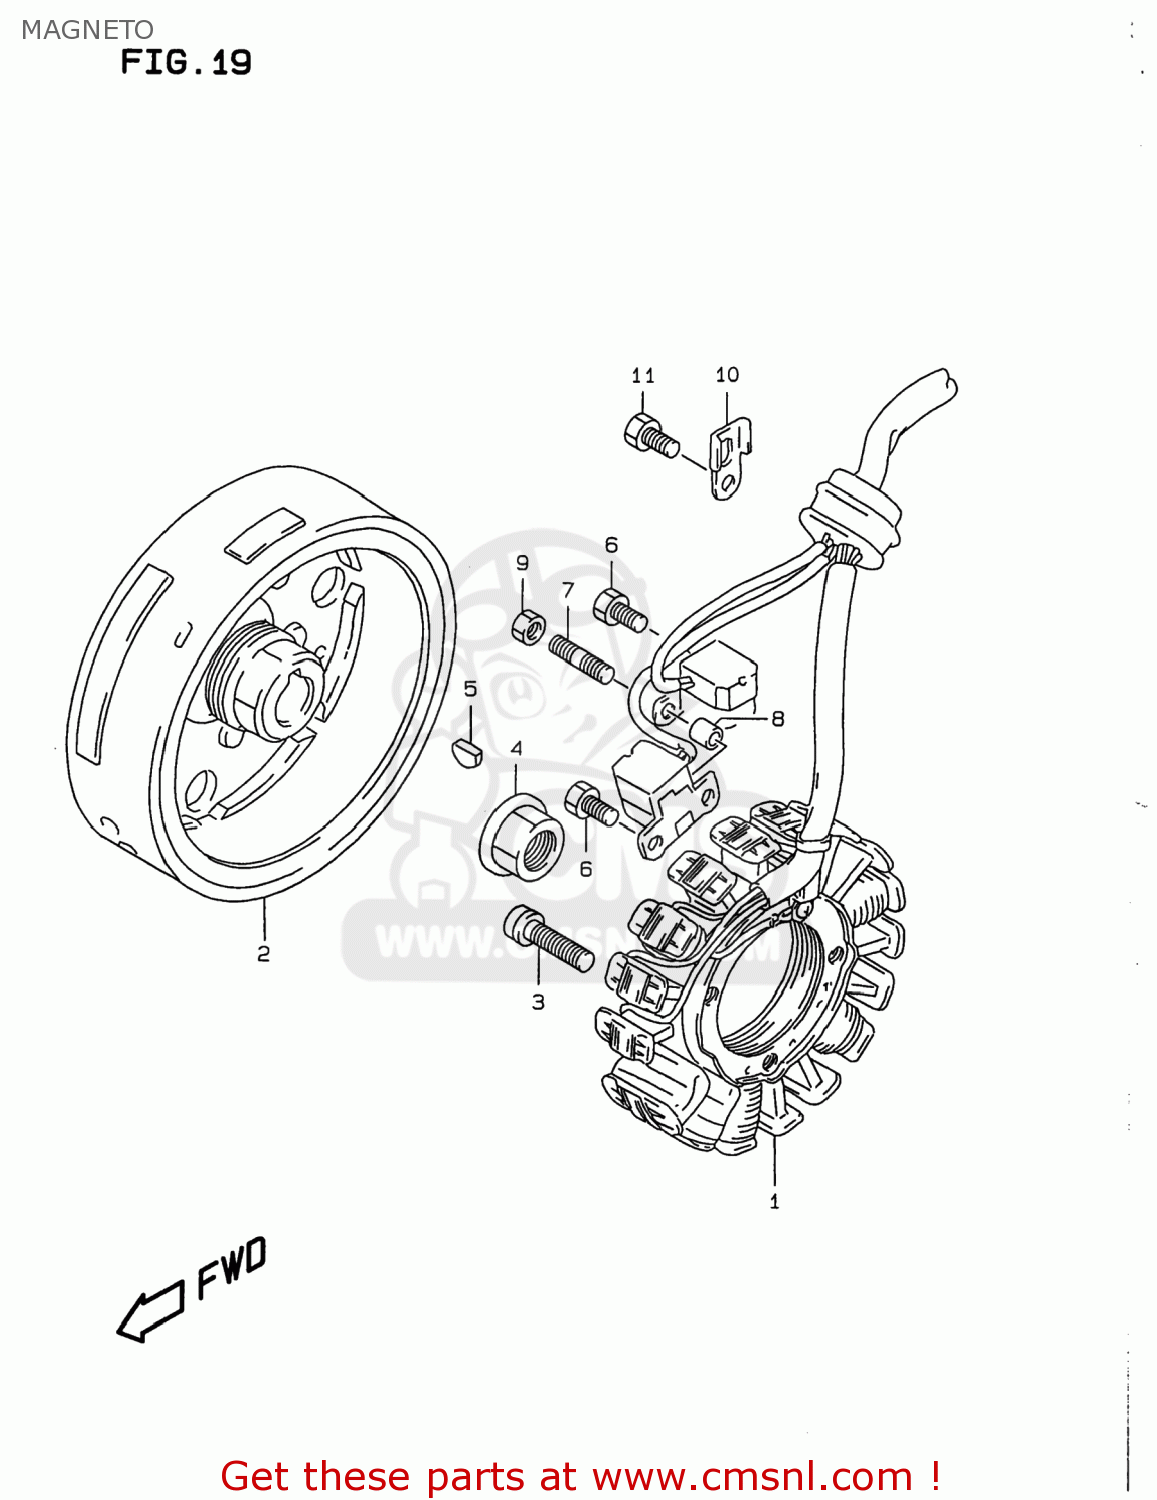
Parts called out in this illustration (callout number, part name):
1	STARTER ASSY
2	ROTOR
3	BOLT,CL.COVER
4	NUT
5	KEY
6	BOLT(5X10)
7	BOLT,STUD(5X18)
8	SPACER(5.5X9.5X6.5)
9	NUT
10	CLAMP,GENERATOR LEAD WIRE
11	BOLT(5X10)
